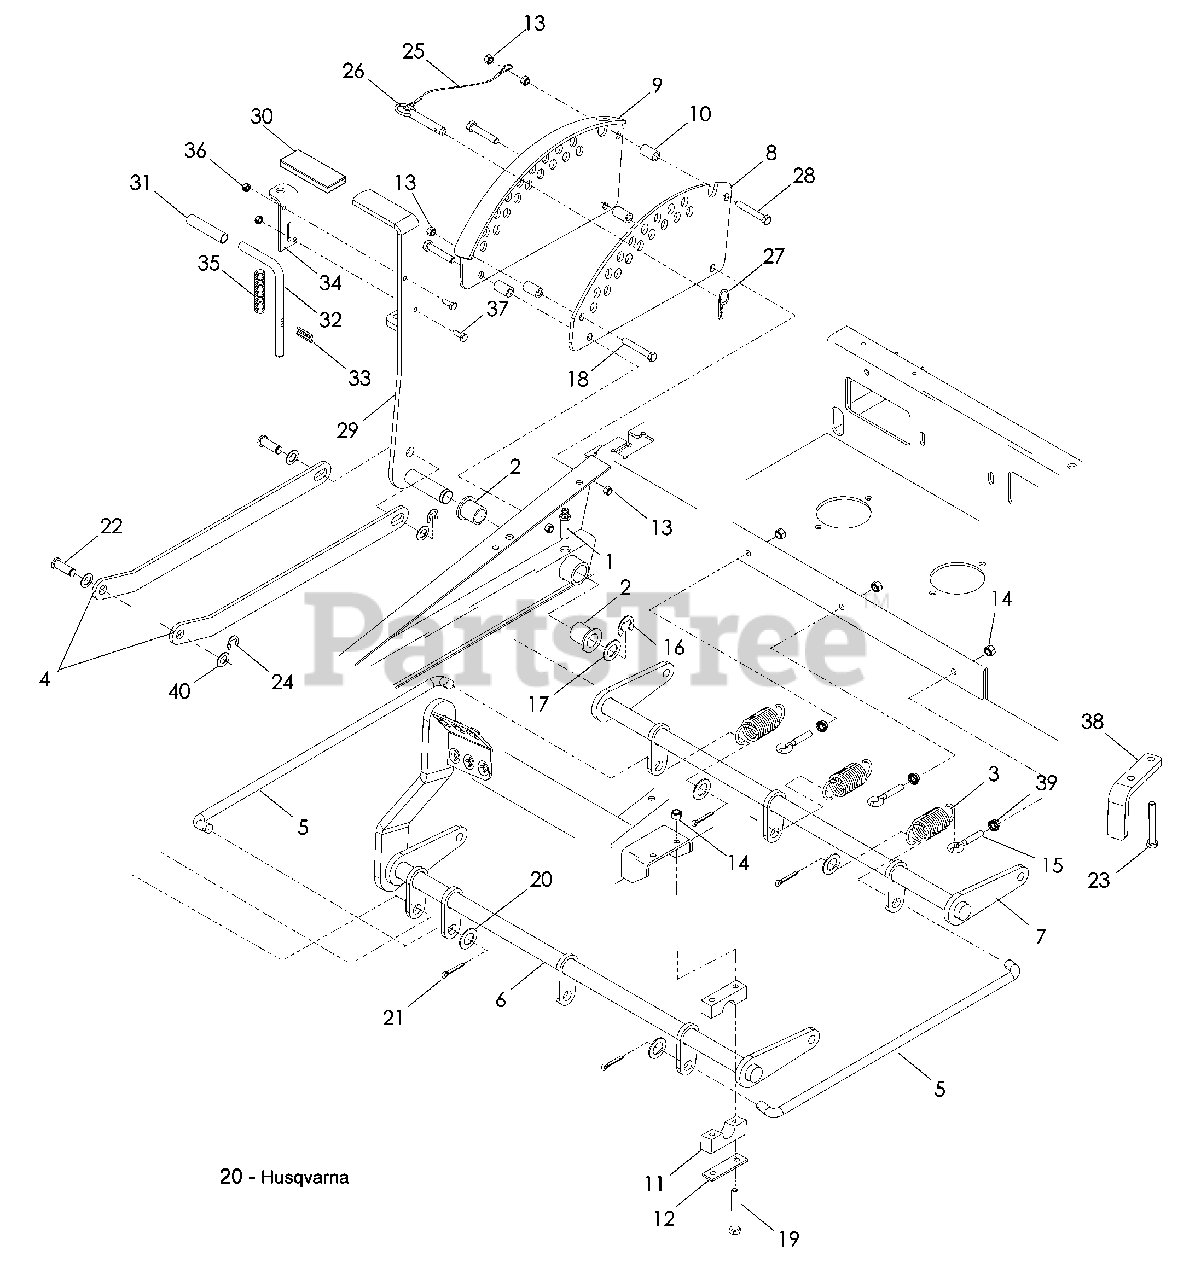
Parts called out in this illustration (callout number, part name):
1	ZERK, LONG
2	BUSHING, FLANGE
3	SPRING, DECK LIFT
4	LINKAGE, LIFT
5	LINK, CONNECTING
6	SHAFT ASSM w/PEDAL, FT
7	SHAFT, REAR LIFT
8	PLATE, ADJUSTMENT
9	PLATE, ADJUSTMENT
10	SPACER, DECK LIFT
11	BLOCKS, PILLOW
12	PLATE, SUPPORT
13	NUT 3/8-16 HEX NYLOC
14	NUT 5/16-18 HEX NYLOC
15	EYEBOLT 5/16
16	E-RING 7/8
17	BUSHING, MACHINE
18	HCS 3/8-16 x 2½
19	HCS 5/16-18 x 2¾
20	WASHER 5/8 SAE
21	PIN, COTTER
22	PIN, CLEVIS 5/8
23	BOLT 3/8-16 x 1 THD FRM
24	E-RING 5/8
26	PIN, HITCH
28	HCS 3/8-16 x 2¾
29	LEVER, LIFT
30	CUSHION, HANDLE
31	GRIP, VINYL
32	PIN, LOCKING
33	PIN, GROOVED
34	PIN MOUNT, UPPER
35	SPRING, COMPRESSION
36	NUT ¼-20 CNTRLK
37	HCS ¼-20 x ¾
38	STOP, DECK
39	NUT 5/16-18 WHIZ
40	BUSHING 5/8
